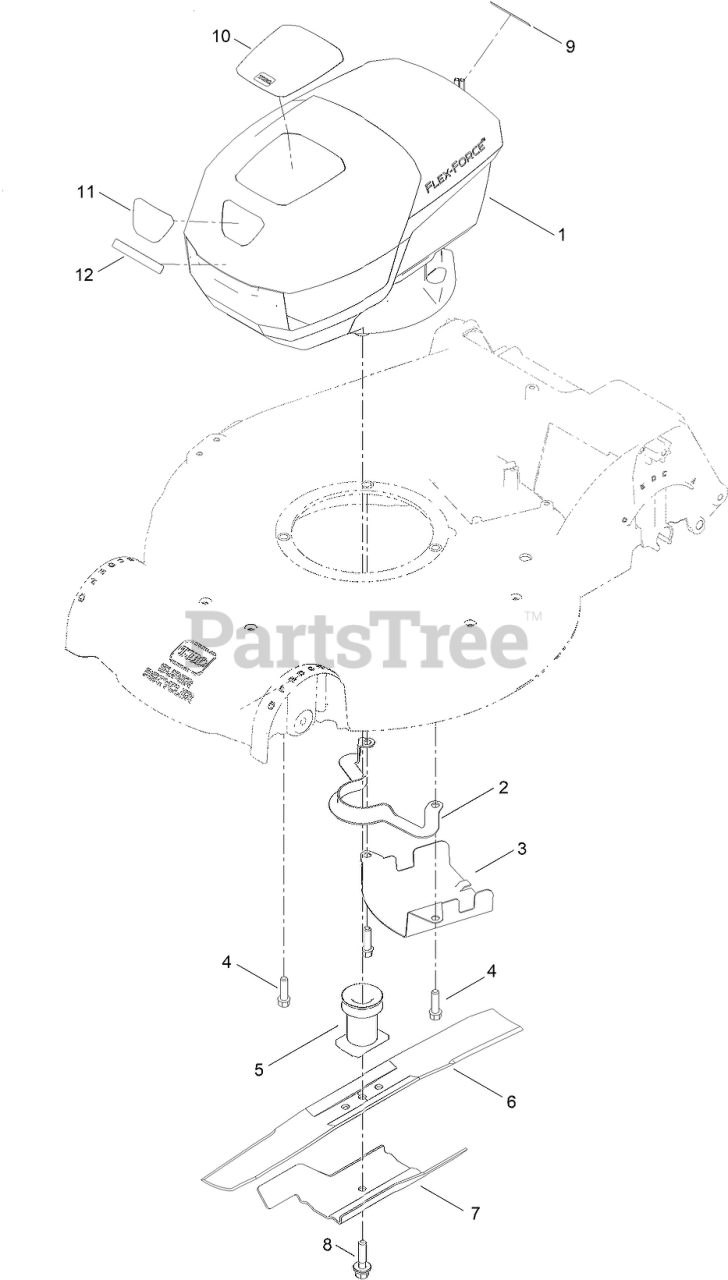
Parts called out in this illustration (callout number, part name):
1	MOTOR MODULE
2	GUIDE-BELT
3	SHIELD-GRASS
4	SCREW-TAPTITE
5	DRIVER-BLADE
6	BLADE-21IN RECYCLING
7	ACCELERATOR-BLADE
8	BOLT-BLADE
9	DECAL-WARNING
